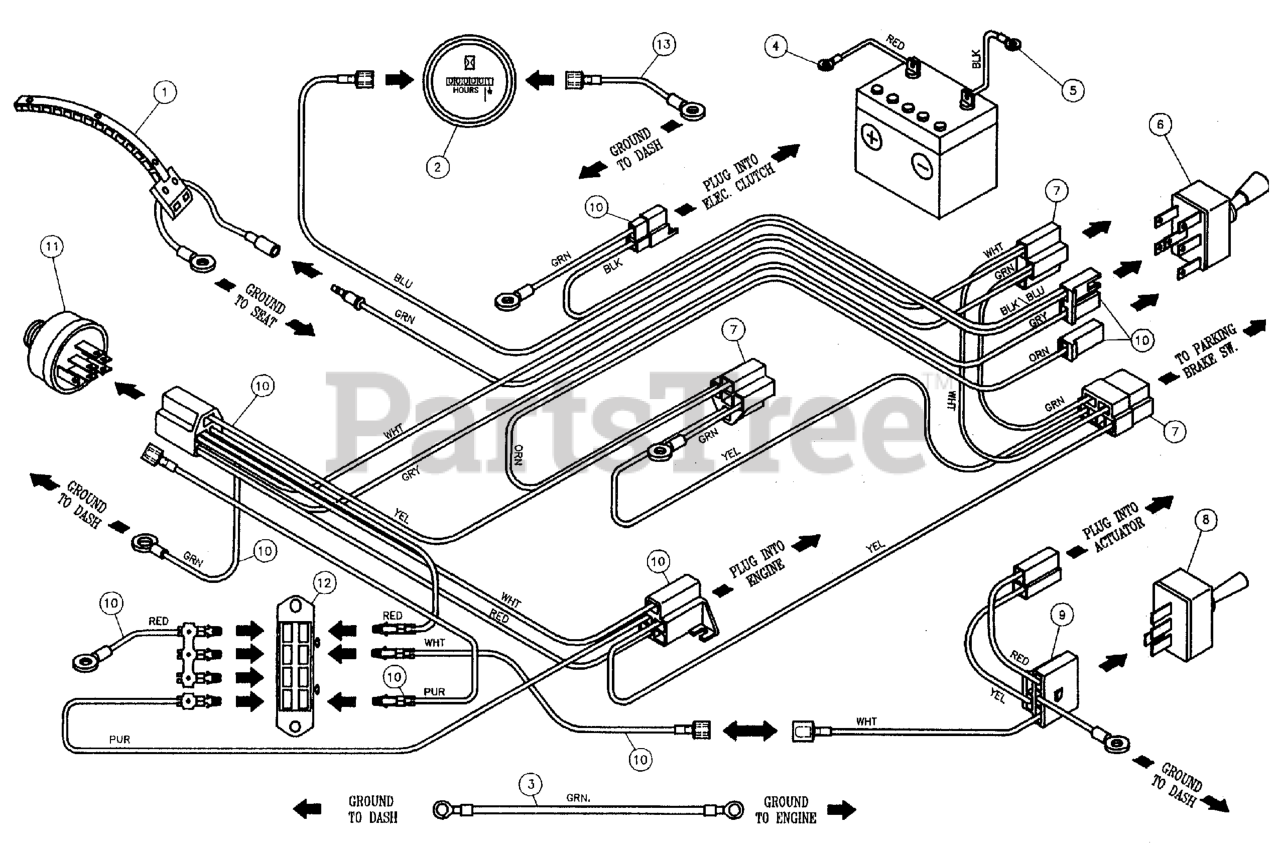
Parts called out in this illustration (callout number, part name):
1	Seat Switch
2	HOUR METER
3	DASH GROUND WIRE
4	POSITIVE (+) BATTERY CABLE, 30"
5	BATTERY CABLE, NEG, 22, 1/4-5/16
6	SWITCH, Electric Clutch
7	Relay Clutch Harness
8	SWITCH, Actuator
9	Actuator Harness
10	Rider Main Harness
11	SWITCH, IGNITION, 6 POST
12	Fuse Block
13	HOUR METER GROUND WIRE
